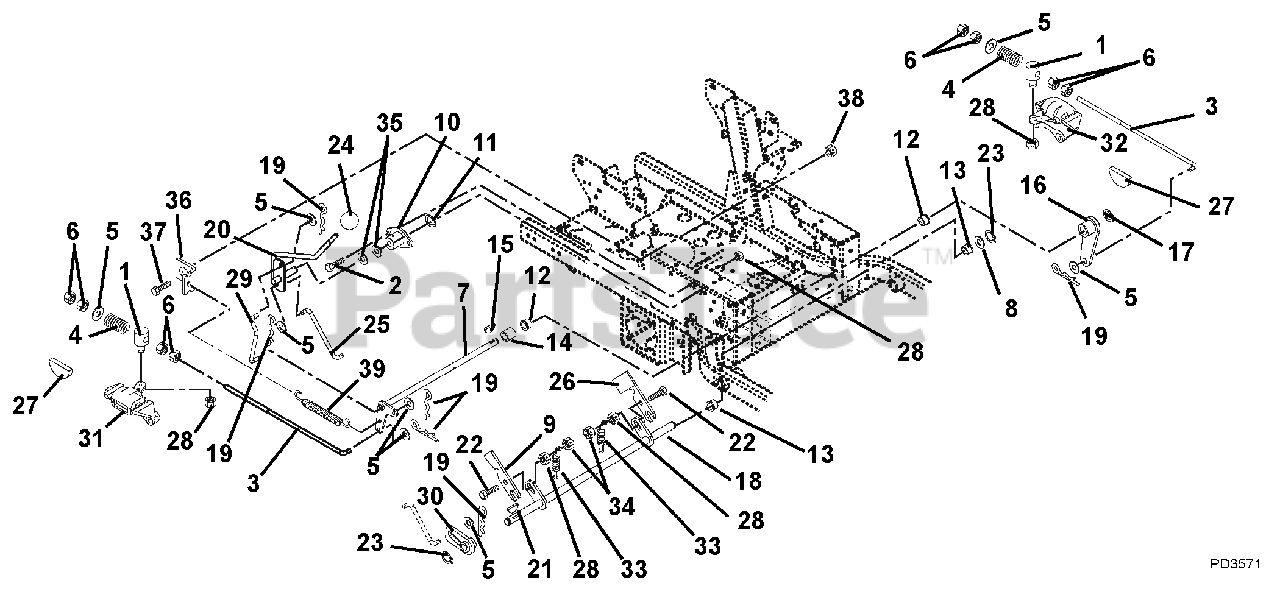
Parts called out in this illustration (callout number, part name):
1	PIN, PIVOT/TRUNNION
2	@BLT-HEX .31-18X.75 GR5 YWZC
3	ROD, BRAKE
4	SG-COMP .142 X .710 X 2.00
5	@WSHR-FL-STL.406X.812X.065 YWZ
6	@NUT-HEX .38-16 YWZC
7	WMT, BRAKE CROSS SHAFT
8	WSHR-FL-STL .505X1.00X.062YWZC
9	SLIDE, INTERLOCKING BRAKE
10	BUSHING, FLANGED
11	RG-RTNG-EXT .625X.050
12	BSHG-FLG .762X1.0X.580X1.48 NY
13	BSHG-FLG .515X.750X.745X1.00NY
14	BSHG-SLV .750X1.000X.750
15	KEY-WDRF .19X.75 HRD #9
16	WMT, BRAKE ARM
17	RG-RTNG-EXT .689X.078
18	WMT, MECHANICAL BRAKE
19	PIN-HAIR, ENDRIES #25 YWZC
20	WMT, BRAKE ACTUATING
21	KEY-WDRF .13X.63 HRD#5
22	@BLT-RDHDSQNK .31-18X1.25 G5YZ
23	RG-RTNG-EXT .500X.050 (SNAP)
24	KNOB-STEERING LOCK
25	LINKAGE, BRAKE ACTUATING
26	INTERLOCK, SAFETY SWITCH
27	PAD SET, DISK BRAKE
28	@NUT-LK-TOP-FLG .31-18 YWZC
29	LINKAGE, BRAKE ACTUATING
30	WMT, PARKING BRAKE HUB
31	BRAKE, RH CALIPER
32	BRAKE, LH CALIPER
33	SG-TENS .061 X .50 X 3.0 WLD 4
34	@NUT-LK-CTR .31-18 YWZC
35	WSHR-FL-STL .630X1.250X.062 YZ
36	BRACKET, SPRING MOUNTING
37	@BLT-HEX .50-13X1.00 GR5 YWZC
38	@NUT-LK-TOP-FLG .50-13 YWZC
39	SPRING, EXT
